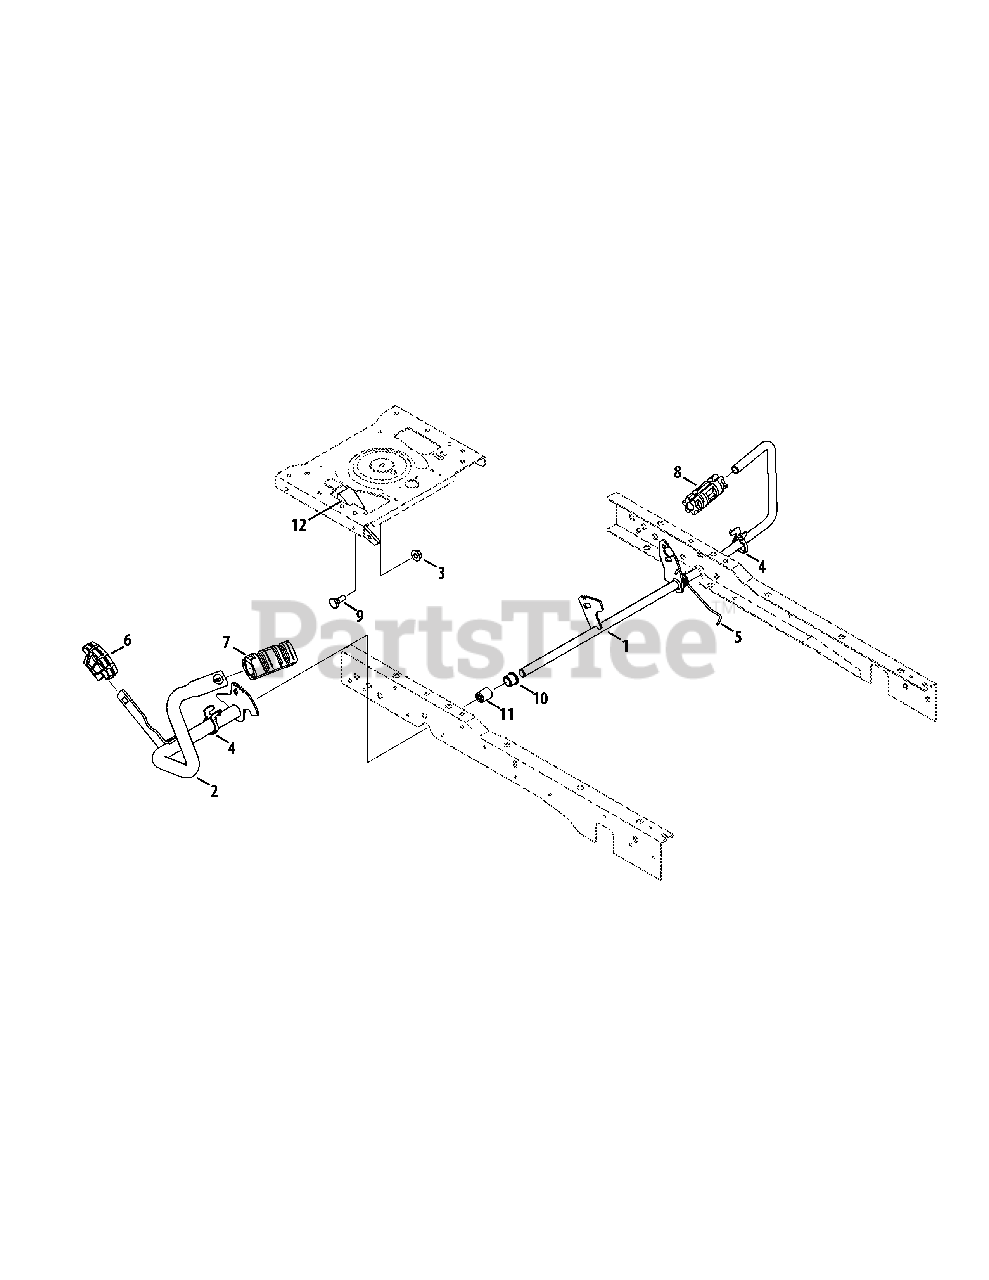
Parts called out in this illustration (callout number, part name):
1	Brake Pedal Assembly
2	FWD/REV Pedal Assembly
3	Flange Lock Nut, 3/8-16
5	Torsion Spring, .725 ID
6	Reverse Pedal Pad
7	Forward Pedal Pad
8	Brake Pedal Pad
9	Shoulder Screw, .50 x .27, 3/8-16
10	Flange Bearing, .63 x .84 x .71
11	Plastic Sleeve Bearing
12	Cruise Latch
